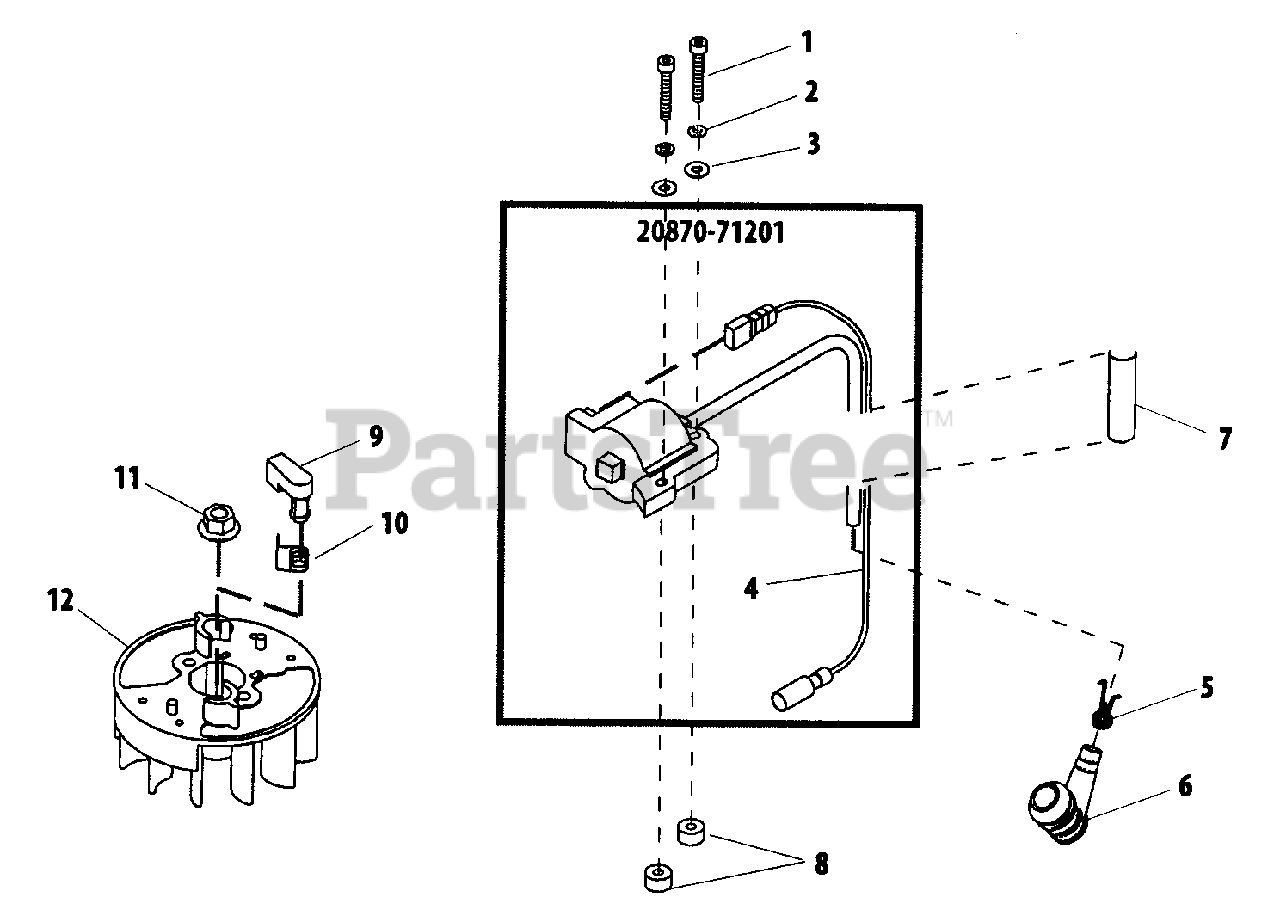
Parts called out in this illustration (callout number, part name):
1	SCREW - 4X26
2	LOCKWASHER - 4
3	WASHER - 4
4	WIRE
5	TERMINAL, SPARK PLUG CAP
6	CAP, SPARK PLUG
7	TUBE
8	INSULATOR
9	PAWL, STARTER
10	SPRING
11	NUT - 8
12	FLYWHEEL
20870-71201	IGNITION COIL ASSY
